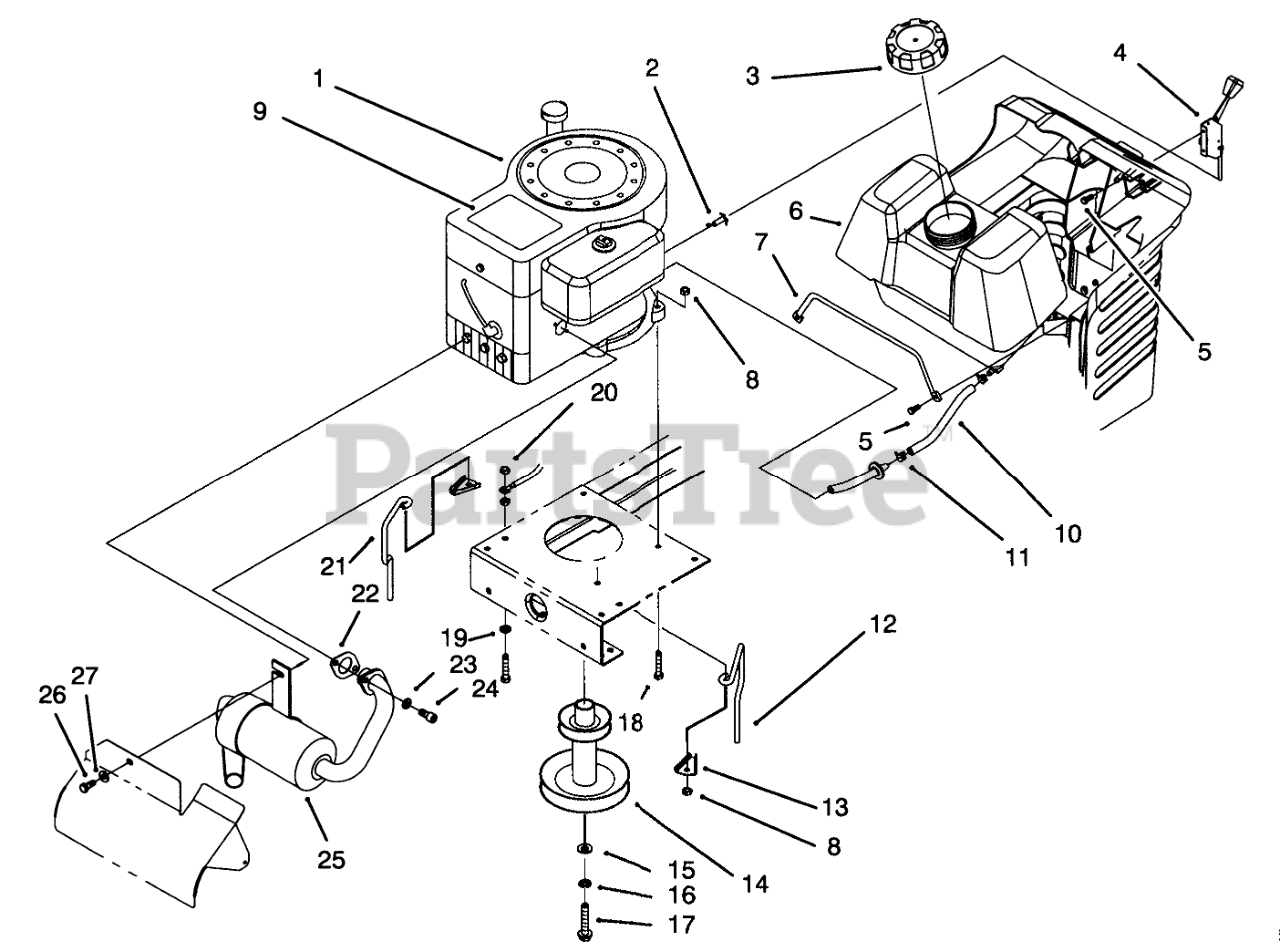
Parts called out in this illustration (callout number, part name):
1	Engine-13 H.P
2	THROTTLE CABLE ASM
3	GAS CAP ASM
4	THROTTLE CONTROL ASM
5	SCREW-SPECIAL
6	GAS TANK ASM
7	GAS TANK ROD
8	NUT-LOCK, NI
9	DECAL - ENGINE
10	HOSE-FUEL
11	CLAMP-HOSE
12	LH BELT GUIDE
13	ANCHOR-GUIDE, BELT
14	ENGINE PULLEY
15	WASHER-FLAT
16	WASHER-LOCK
17	SCREW-HH
18	SCREW-HH
19	WASHER-LOCK
20	NUT-KEPS
21	RH BELT GUIDE
22	GASKET-EXHAUST
23	WASHER-LOCK
24	SCREW-HSH
25	MUFFLER
26	SCREW-HH
27	WASHER-LOCK
